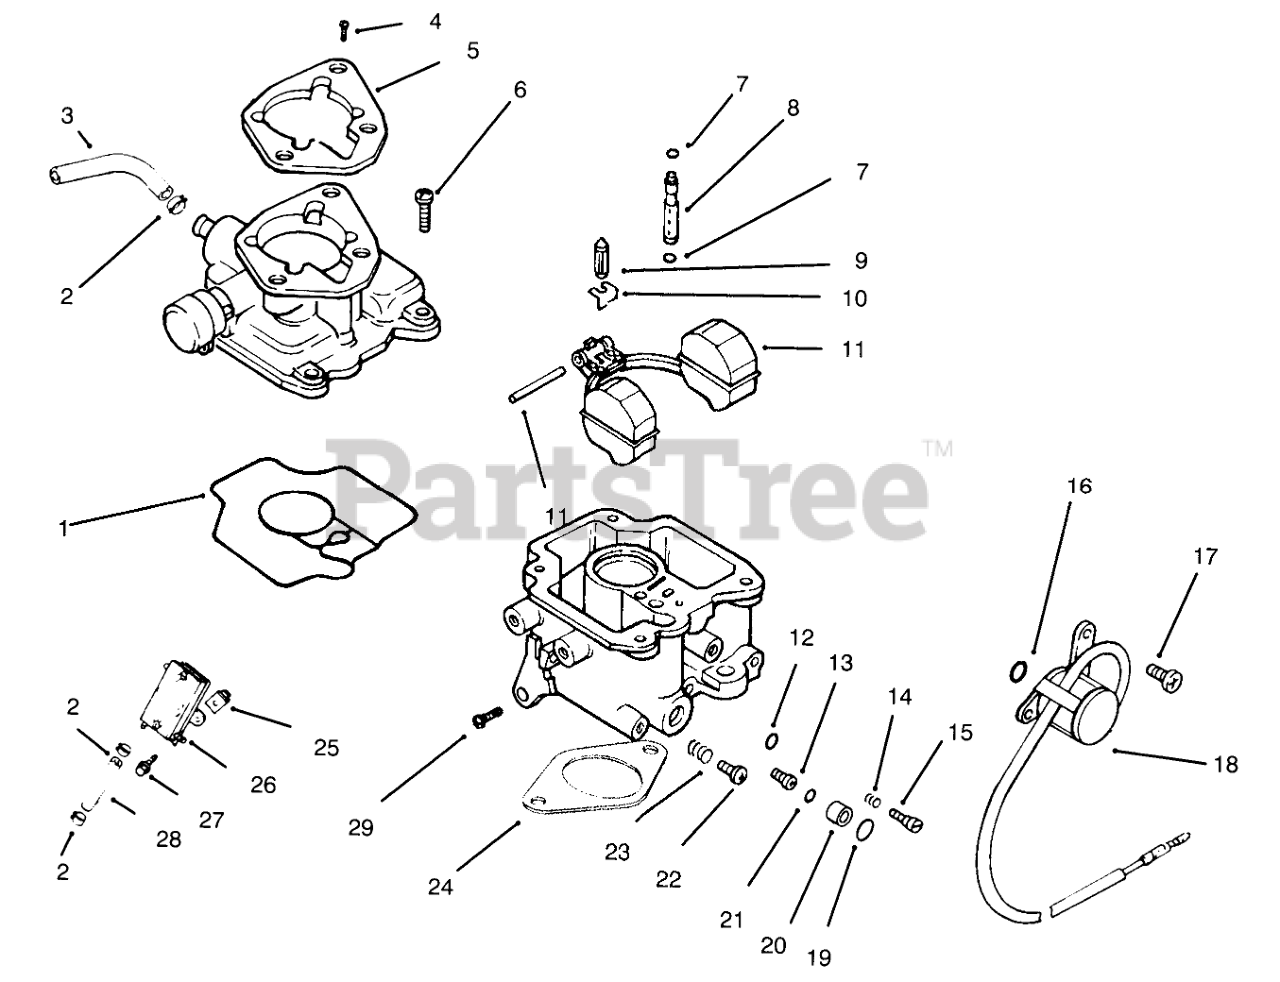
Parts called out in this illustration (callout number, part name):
1	Gasket-Carburetor Body
2	Clamp
3	Line-Fuel
5	Gasket-Air Cleaner
7	"O"Ring
8	Jet-Slow
9	Valve-Inlet Needle
10	Clip-Inlet Needle Valve
11	Kit-Float Repair
12	"O"Ring
13	Jet-Main
14	Spring-Idle Adjust
15	Needle-Idle Adjust
16	"O"Ring
18	Solenoid
19	"O"Ring
20	Seat-Solenoid
21	"O"Ring
22	Screw-Idle Speed Adjust
23	Spring-Idle Speed Adjust
24	Gasket-Carburetor
26	Pump-Fuel
28	Line-Fuel 15-1/2"
29	Screw-Throttle Stop
